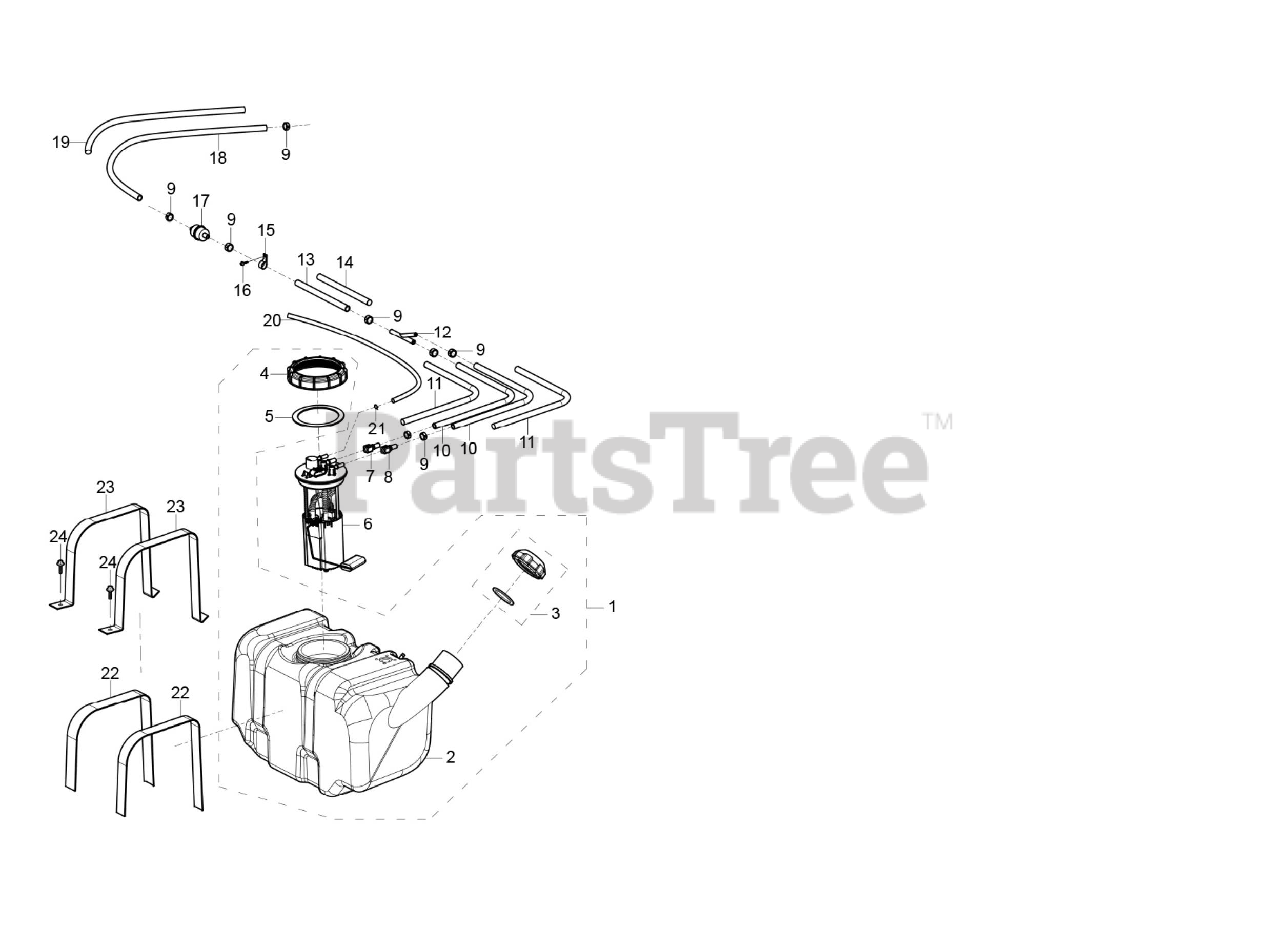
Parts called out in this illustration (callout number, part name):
1	FUEL TANK ASSEMBLY
2	Fuel tank
4	FUEL PUMP RETAINING CAP
5	Seal Gasket B For Fuel Pump
6	Fuel Pump
7	Fuel outlet Plug
8	FUEL INLET CONNECTOR
9	Pressure Clamp A
10	FUEL LINE - 0.05MPA?
11	Thermal insulation bellows II,Aluminum Foil
12	Triplet Joint Fuel Pipe
13	FUEL LINE - 0.05MPAIII
14	HEAT INSULATION HOSEIII
15	BRAKE LINE CLIP?
16	Hexagon Flange Bolt M6x16
17	FUEL FILTER
18	FUEL LINE - 0.05MPAIV
19	HEAT INSULATION HOSE IV
20	FUEL LINE - EPA7x11x700
22	TANK FOAM
23	Fuel Tank holddown
24	Hexagon Flange Bolt M8x30
